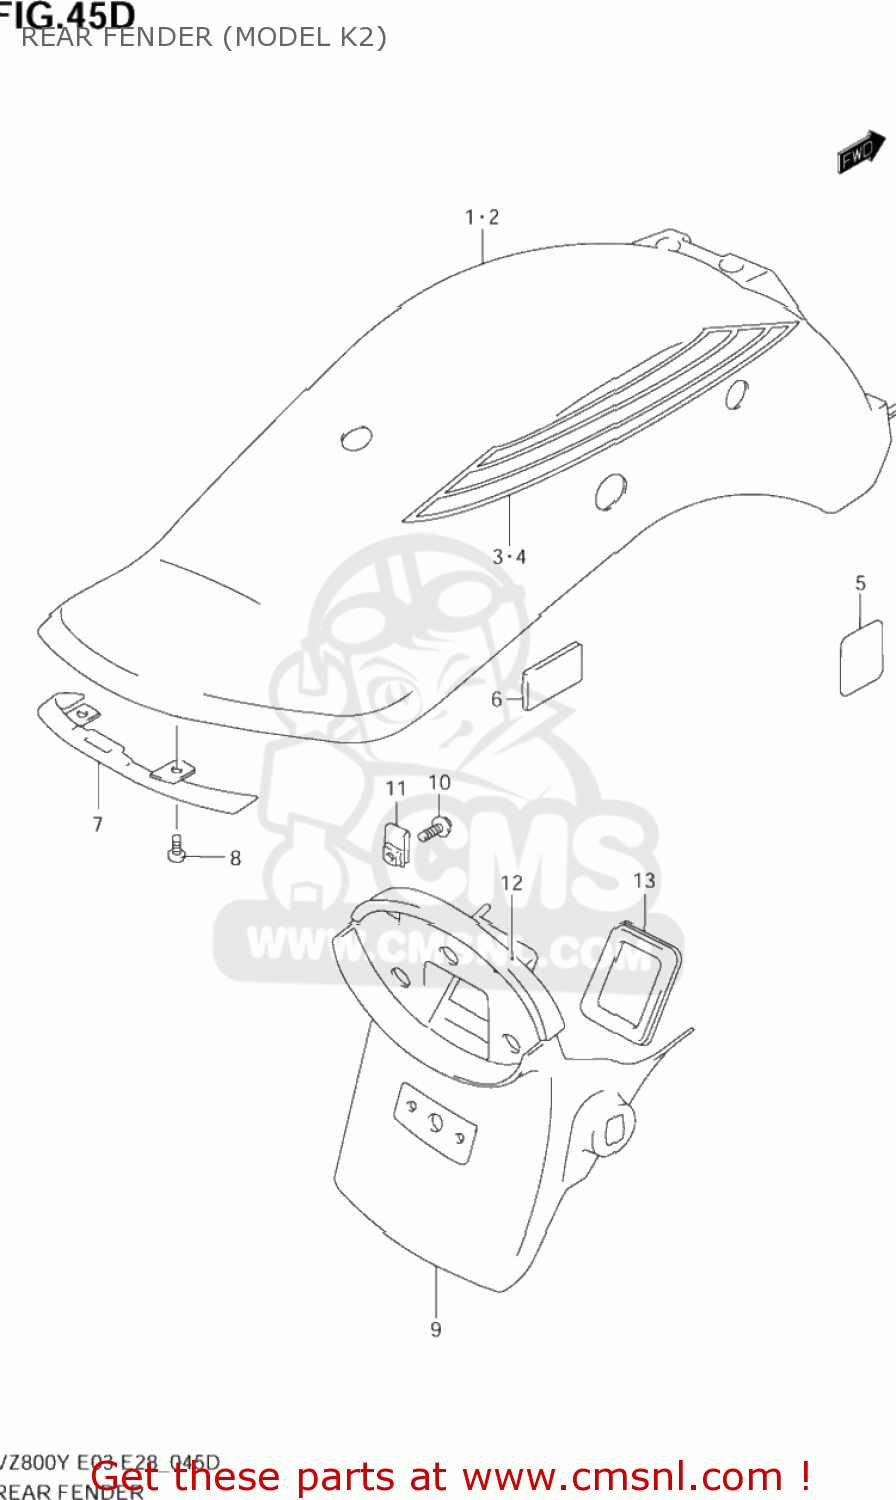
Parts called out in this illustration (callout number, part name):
1	FENDER,RR
2	FENDER,RR
3	TAPE,RR FENDER,R
4	TAPE,RR FENDER,L
5	PAD
6	CUSHION
7	COVER,RR FENDER RR
8	SCREW
9	EXTENSION,RR FENDER
10	SCREW
11	PLATE,FRAME COVER
12	CUSHION,RR FENDER EXTENSION
13	CAP,RR FENDER EXTENSION
